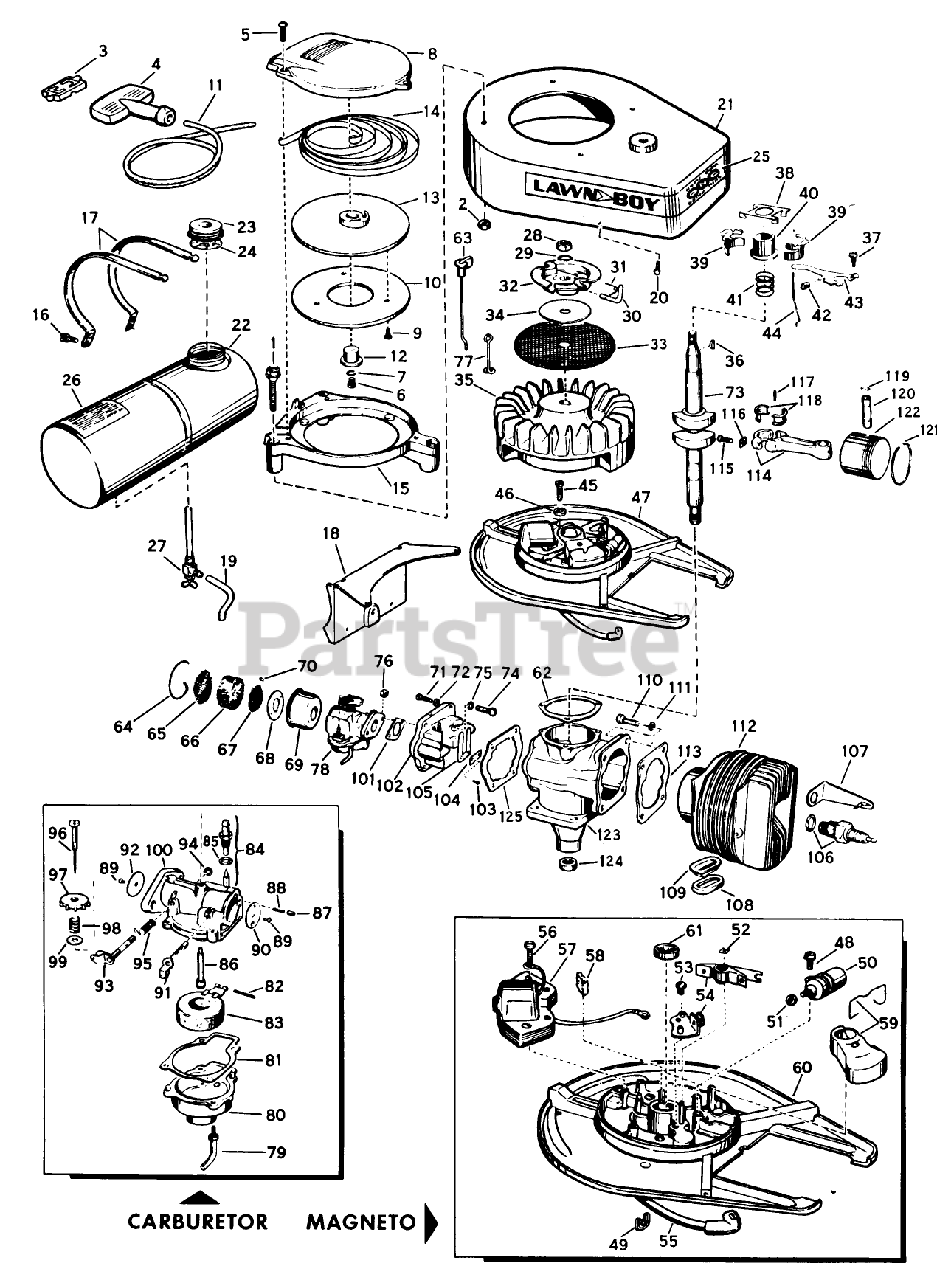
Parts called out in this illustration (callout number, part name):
10	Plate-Pulley
14	RECOIL SPRING
20	SCREW S
23	Gas Cap
25	Decal-"Lawn-Boy"
27	VALVE&SCREEN SM
30	PIN - STARTER
40	COLLAR S
42	WEAR BLOCK S
43	GOVERNER LEVER AY
44	GOVERNOR ROD S
54	BREAKER AY. S
62	GASKET S
66	ELEMENT
68	BACK-UP PLATE
71	SCREW S
76	STOP NUT
77	Stop-Choke Link
89	Screw-Choke Disc
95	SPRING
96	NEEDLE AY. S
98	Spring-Ndl. Adj.
101	GASKET S
104	PLATE-BACKUP, REED
106	Spark Plug
112	Cylinder Sleeve Assembly
118	LINER ASM
121	Ring-Piston
